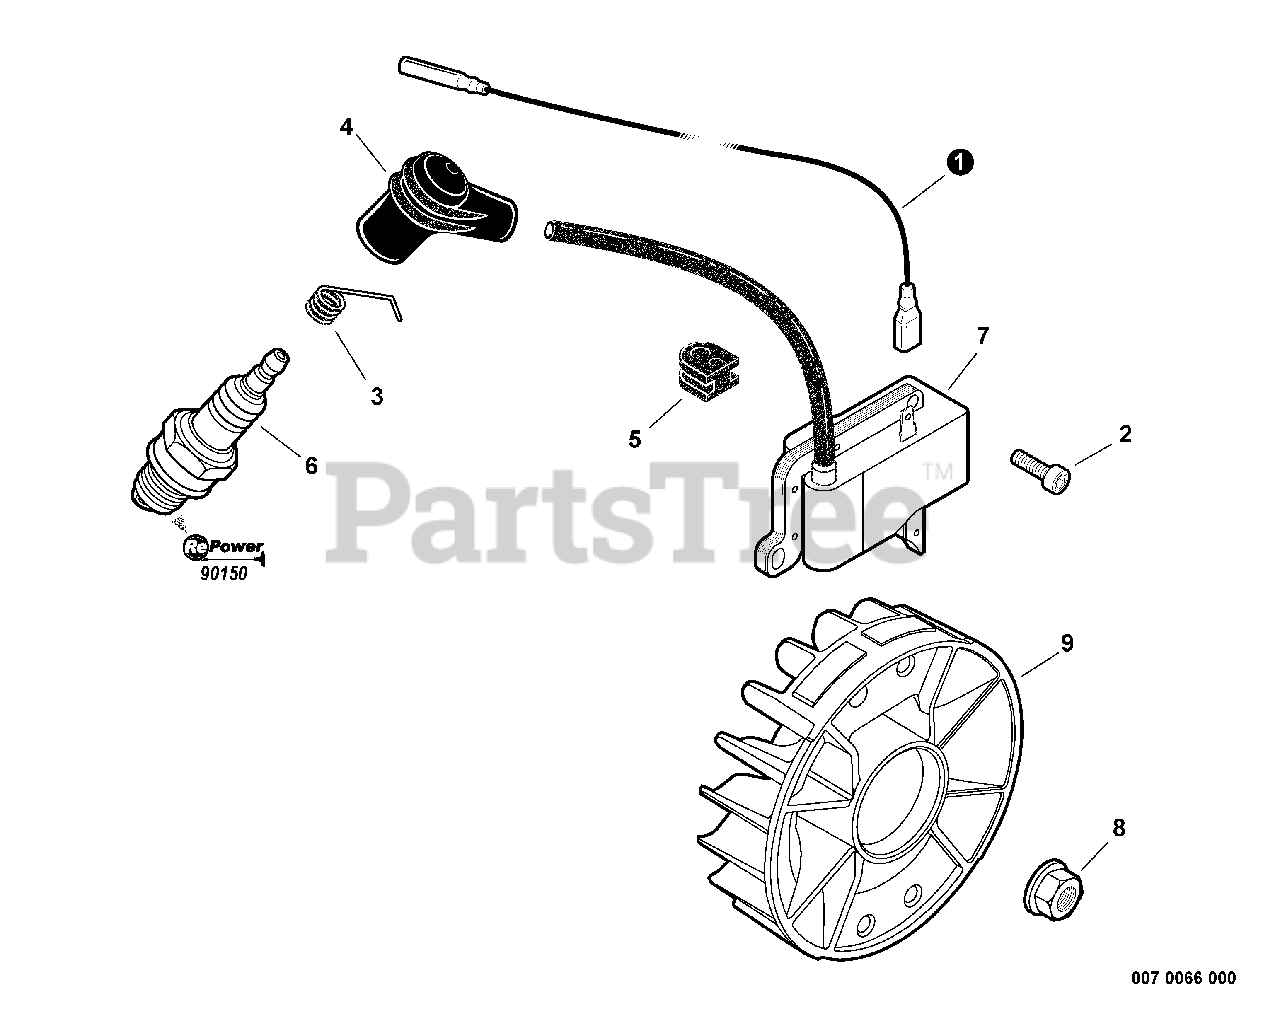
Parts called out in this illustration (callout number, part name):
1	LEAD - IGNITION
2	SCREW - 5X20
3	TERMINAL, SPARK PLUG CAP
4	CAP, SPARK PLUG
6	SPARK PLUG -- BPM-6Y
6	SPARK PLUG -- BPMR-6Y
7	COIL, IGNITION
8	NUT - 10 -- FLANGE
9	FLYWHEEL
10	RePower TUNE-UP KIT
